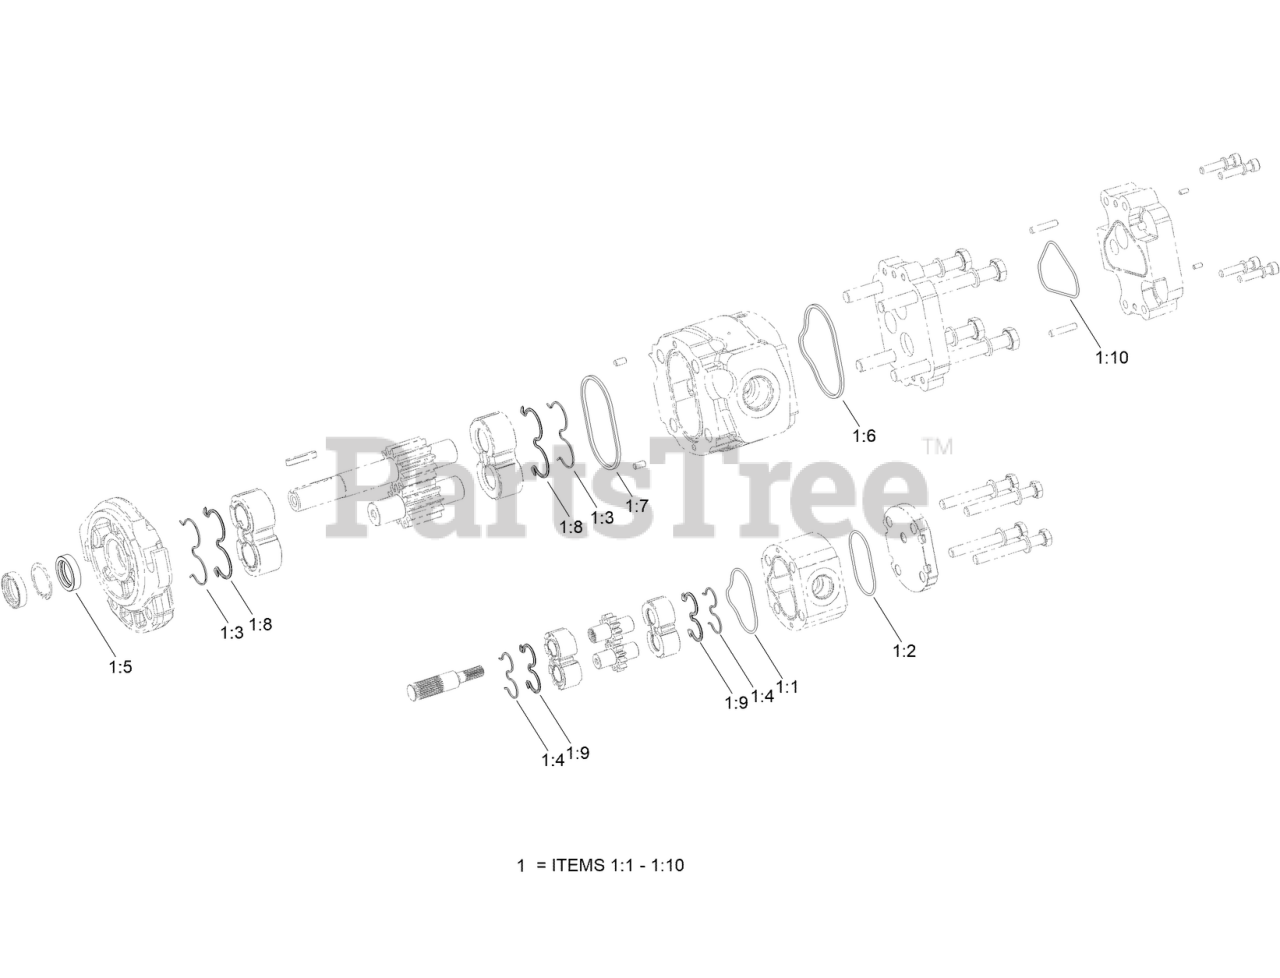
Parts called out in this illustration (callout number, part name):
1	SEAL KIT
1:1	O-RING
1:2	O-Ring Seal
1:3	ANTI-EXTRUSION
1:4	ANTI-EXTRUSION
1:5	SHAFT SEAL
1:6	SEAL
1:7	STANDARD SEAL
1:8	SEAL
1:9	SEAL
1:10	O-Ring Seal
